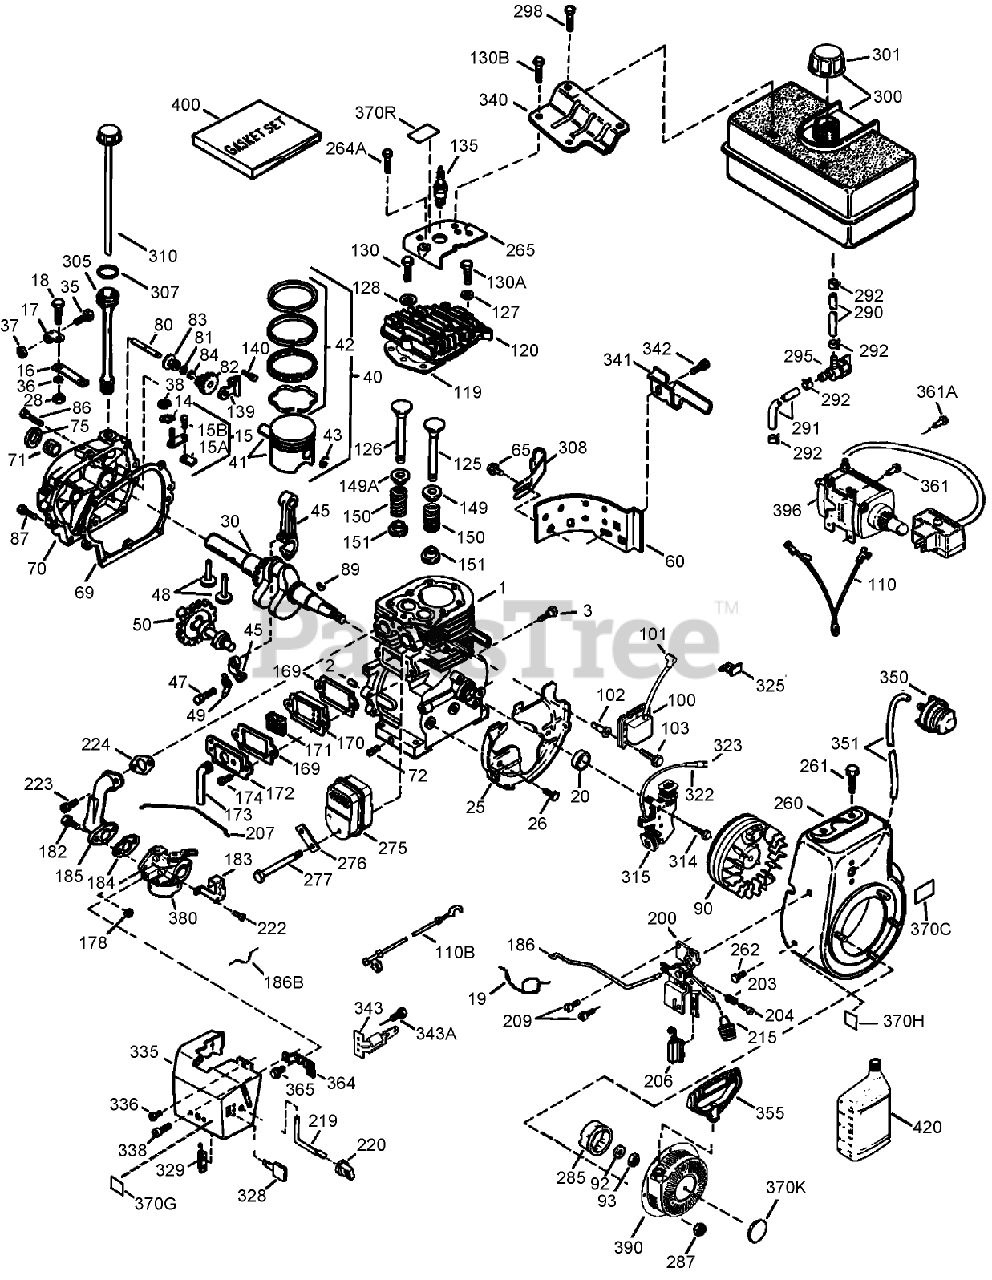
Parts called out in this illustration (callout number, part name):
1	Cylinder (Incl. ref. #2 20)
2	Pin-Dowel
3	Screw (1/4-20x1/2)
14	Washer-Flat
15	Rod, Governor (Incl. Nos.62 63)
15A	Yoke-Governor
15B	Screw (6-40x5/16)
16	Lever-Governor
17	Clamp-Lever, Governor
18	Screw (T-15, 8-32x7/16)
19	Spring-Throttle
20	Seal-Oil
25	Baffle-Housing, Blower
26	Screw (1/4-20x19/32)
28	Nut-Lock
30	Crankshaft
35	Screw
36	Washer-Lock
37	Nut-Lock
38	Ring-Retaining
40	Piston Pin and Ring ASM (STD)
40	Piston Pin and Ring ASM (.010)
40	Piston Pin and Ring ASM (.020)
41	Piston Pin Ass-y(Std.)(Incl. 43)
41	Piston Pin Ass-y (.010" OS)(Incl. 43)
41	Piston Pin Ass-y.(.020" OS)(Incl. 43)
42	Ring Set (STD)
42	Ring Set (.010)
42	Ring Set (.020)
43	Retaining Ring-Piston Pin
45	Connecting Rod ASM (Incl. Ref. #47)
47	Bolt-Rod, Connecting
48	Lifter-Valve
49	Dipper-Oil
50	Camshaft (MCR)
60	Extension-Housing, Blower
65	Screw
69	Gasket-Cover, Cylinder
70	Cover-Cylinder (Includes 71, 75, 80 - 84)
71	2025A77 WIZARD ROTA
72	Plug-Drain, Oil (SQH 1/4-18)
75	Seal-Oil
80	Shaft-Governor
81	Washer
82	Governor Gear ASM
83	Spool-Governor
84	Ring-Retaining
86	Screw (1/4-20x1-3/16)
87	Screw (1/4-20x1-11/16)
89	Key-Flywheel
90	Flywheel ASM
92	Washer-Belleville
93	Nut-Flywheel
100	Ignition-Solid State
101	Cover-Spark Plug
102	Stud-Mounting, Solid State
103	Screw (T-15, 10-24 x 15/16)
110	Wire-Ground
110B	Wire-Ground
119	Gasket-Head, Cylinder
120	Head-Cylinder
125	Valve, Exhaust (Standard)(Incl. No. 9)
125	Valve, Exhaust (1/32" oversize)(Incl. No. 9)
126	Valve, Intake (Std.) (Incl. Ref. #58)
127	Washer-Flat
128	Washer-Belleville
130	Screw (5/16-18x1-1/2)
130A	Screw (5/16-18x1-25/32)
130B	Screw (5/16-18x39/64)
135	Spark Plug-Resistor (R J19 L M)
139	Bracket-Gear, Governor
140	Screw (10-24x1/2)
149	Cap-Spring, Valve
149A	51106 GILSON ROTARY
150	Spring-Valve
151	Keeper-Spring, Valve
169	Gasket-Cover, Valve
170	Body-Breather
171	Element-Breather
172	Cover-Valve
173	Tube-Breather
174	Screw
178	Nut and Lock Washer (1/4-28)
182	Screw (1/4-28x1)
183	Bracket-Choke
184	Gasket-Carburetor To Intake Pipe
185	Pipe-Intake
186	Link-Governor
186B	Spring-Choke
200	Bracket-Control (Includes 19, 203, 204, 206)
203	Spring-Compression
204	Screw (T-10, 5-40x7/16)
206	Terminal
207	Link-Throttle
209	Screw (10-32 x 1/2)
215	Knob-Control
219	Rod-Choke
220	Knob-Control
222	Screw (10-32 x 1/2)
223	Screw (T-30, 5/16-18x1-3/32)
224	Gasket-Pipe, Intake
260	Housing-Blower
261	Screw (5/16-18x3/4)
262	Screw (5/16-18x9/16)
264A	Screw (1/2-20x5/8)
265	Cover-Head, Cylinder (Black)
275	Muffler
276	62513 SNWTHWR W/284
277	Screw (5/16-18x4-3/16)
285	Cup-Starter
287	Nut and Lock Washer (1/4-28)
290	Line-Fuel
291	Line-Fuel (8.62)
292	Clamp-Line, Fuel
295	Valve-Shut Off, Fuel (Includes 292)
298	Screw (1/4-15x7/8)
300	Tank-Fuel (Includes 292, 301)
301	Cap-Fuel (Black) (1-1/2 I D)
305	Tube-Fill, Oil
307	O-Ring
308	Clip-Tube, Fill
310	Dipstick
314	Screw (1/4-20 x 3/4)
315	Coil-Alternator, 18 Watt (Includes 323)
322	Body-Connector
323	Terminal
325	Clip-Wire
328	Key-Ignition
329	Terminal
335	Cover-Carburetor (Black)
336	Screw (10-32x1/2)
338	Screw (10-32 x 3/8)
340	Bracket-Tank, Fuel (Black)
341	Bracket-Tank, Fuel
342	Screw (1/4-20x19/32)
343	Bracket-Switch, Key
343A	Screw (8-32 x 23/64)
350	Primer ASM
351	Line-Primer
355	Handle-Starter, Mitten Grip
361	Screw (T-30, 1/4-20x15/32)
361A	Screw
364	Bracket-Cover, Carburetor
365	Screw (8-32x27/64)
370C	Decal-Primer, International Symbol
370G	Decal-Instruction
370H	Decal-Speed Control and Choke
370K	Decal-Tecumseh Logo for Top of Recoil Starter
370R	Decal-Warning (Bilingual)
380	Carburetor ASM (Includes 184)
390	Starter-Rewind
396	Starter-Electric (110 Volt)
400	Gasket Set
420	Oil-Engine, S A E 5W30
